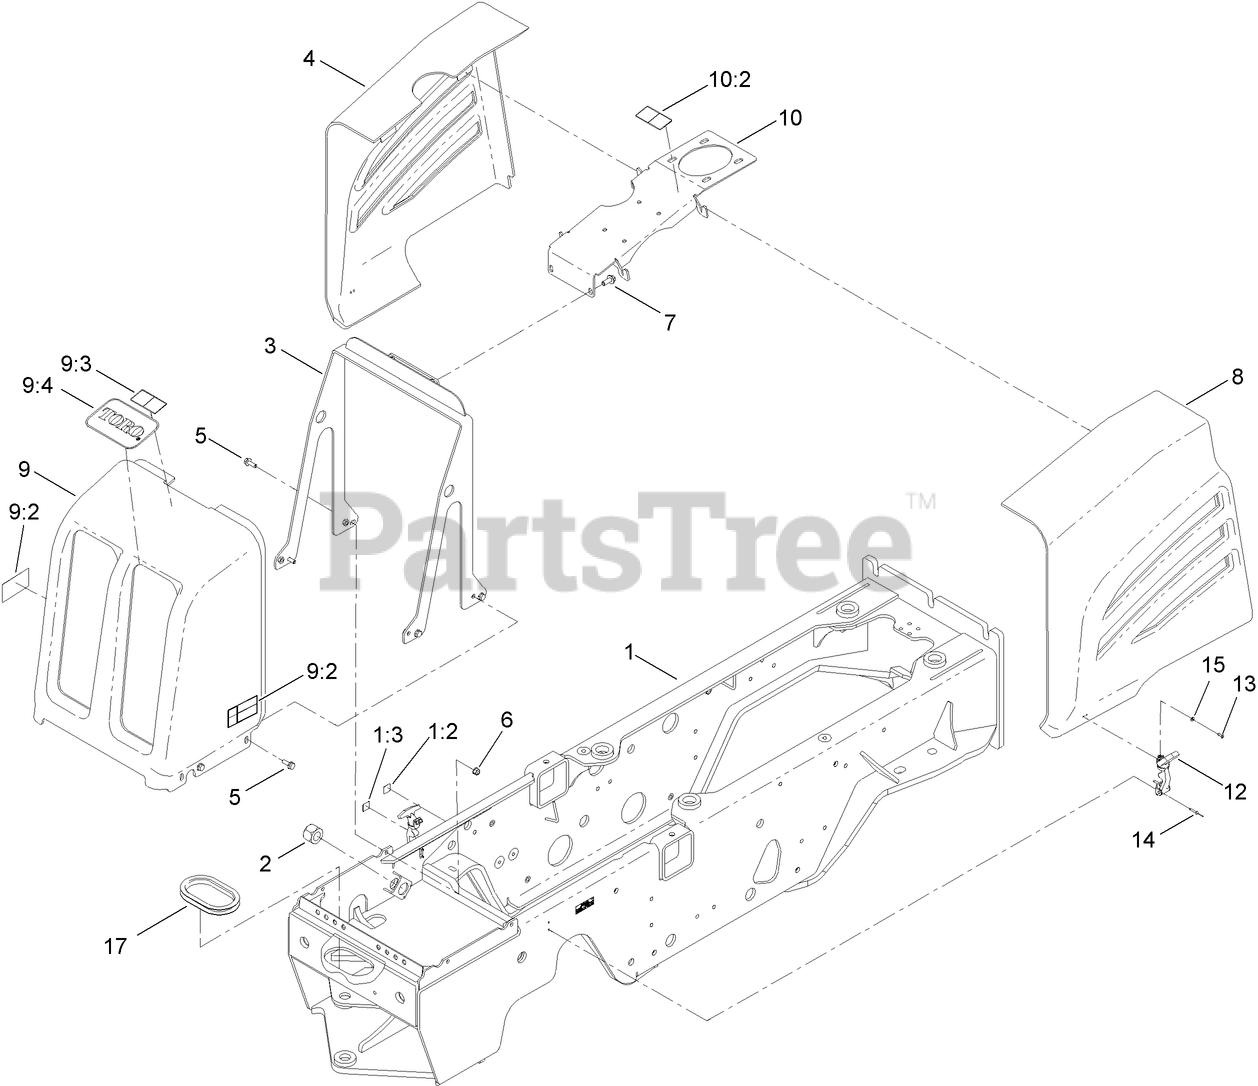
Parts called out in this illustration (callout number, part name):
1	CHASSIS FRAME ASM
1:2	DECAL-FLUID, HYDRAULIC (OUT)
1:3	DECAL-FLUID, HYDRAULIC (IN)
3	SUPPORT-HOOD
4	HOOD-RH
5	SCREW-HHF
6	NUT-LOCK, NI
7	SCREW-HHF
8	HOOD-LH
9	NOSE CLIP ASM
9:2	DECAL-WARNING, FAN
9:3	DECAL-WARNING, RADIATOR
9:4	DECAL
10	HOOD SUPPORT ASM
10:2	DECAL-SURFACE, HOT
12	LATCH-DRAW, FLEXIBLE
13	RIVET-POP
14	RIVET-BLIND
15	WASHER-PLAIN
17	TRIM-EDGE
